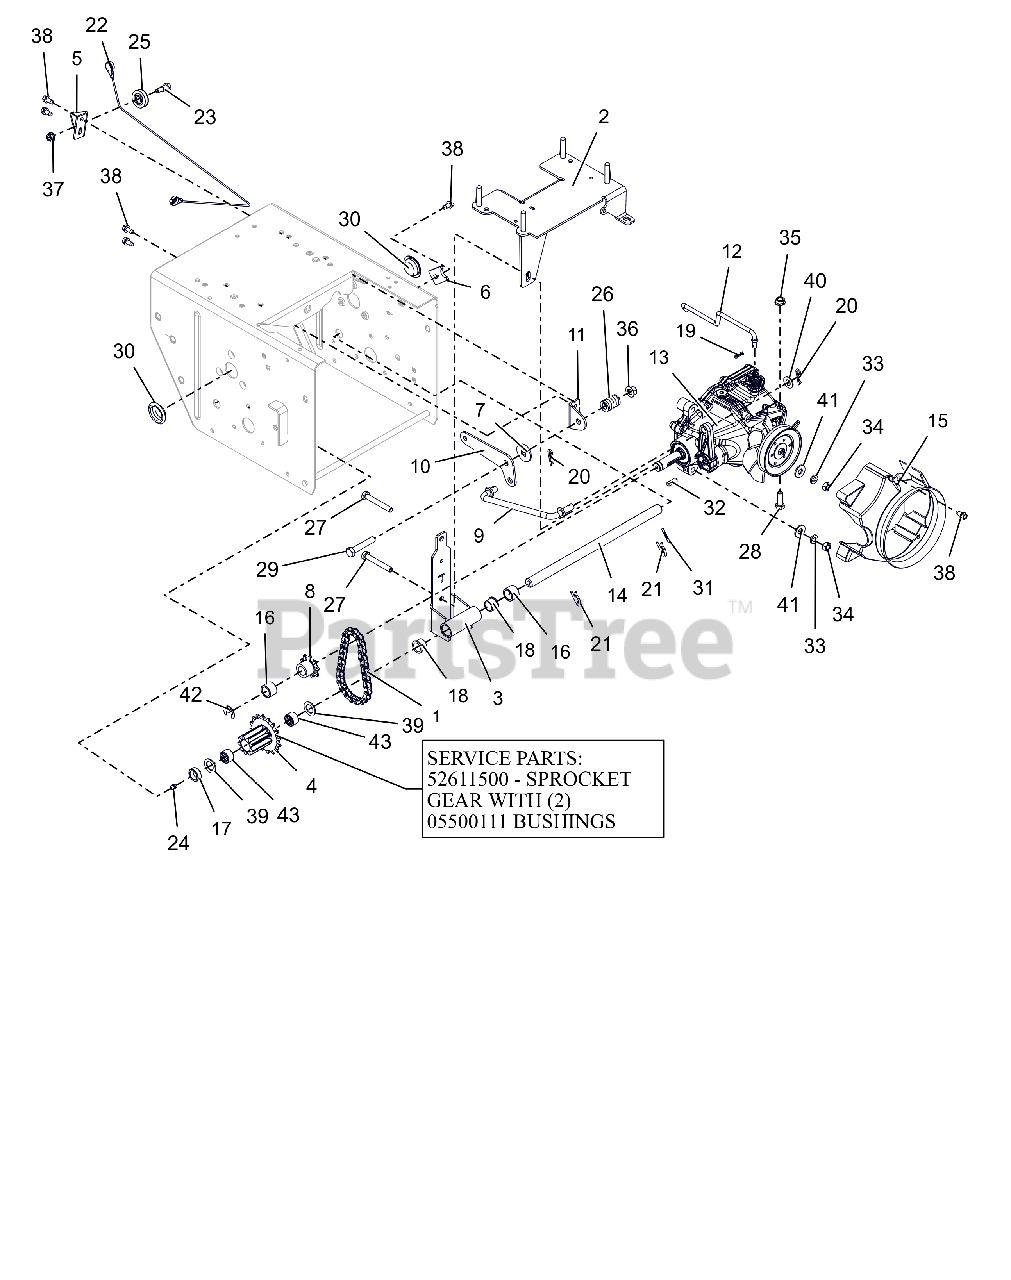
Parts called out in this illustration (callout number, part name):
1	CHAIN-ROLLER #41X26 PITCHES
2	BRACKET, HYDROSTATIC TRANS XLG
3	TRANS MOUNT, TENSIONING, TRACK
4	PINION & SPROCKET (16T & 9T)
4	PINION & SPROCKET W/BEARINGS
5	BRACKET, CABLE PULLEY
6	TAB, ANTI ROTATION
7	FRICTION WASHER
8	SPROCKET, PINION 9T W/KEY
9	ROD, HYDRO TRANS SHIFT
10	PIVOT, HYDRO TRANS SHIFT
11	BRACKET, HYDRO SHIFT PIVOT
12	ROD, HYDRO BYPASS
13	TRANSMISSION, HYDROSTATIC
14	SHAFT, PINION - HARDENED
15	SHROUD, HYDROGEAR RT-310
16	SPACER, .635X.880X.611
17	BSHG-SLV, .635X.880X.305
18	BSHG-FLG .625X.750X.500X.875
19	PIN-HAIR INT .06X.18X.77
20	PIN-HAIR INT .08X.18X1.18 YWZC
21	PIN, SPRING CLIP
22	CABLE, TRACTION, HYDRO PRO
23	BOLT, SHLDR-.375X.375X.25-20
24	ZERK,FITTING .25X.125 DRIVE IN
25	PULLEY, CABLE
26	SG-COMP .187X.56X1.62
27	@BLT-HEX .31-18X2.25 GR5 YWZC
28	@BLT-HEX .31-18X1.00 GR5 YWZC
29	@BLT-HEX .38-16X2.00 GR5 YWZC
30	PLUG, HOLE - 1.125"
31	@PIN-GRV .125X1.00 TP E ALLOY
32	KEY-SQ .188X.75X.188
33	WSHR-LK .312X.097 HVY YWZC
34	@NUT-HEX .31-18 YWZC
35	@NUT-LK-TOP-FLG .31-18 YWZC
36	@NUT-LK-TOP-FLG .38-16 YWZC
37	@NUT-LK-TOP-FLG .25-20 YWZC
38	SCR-TAP .25-20X.50 HWH TR YWZ
39	WSHR-FL-STL .630X1.005X.062 YZ
40	@WSHR-FL-STL.406X.812X.065 YWZ
41	@WSHR-FL-STL.38X.875X.083 YWZC
42	RG-RTNG-EXT .625X.042
43	BRG-NEEDLE .625X.812X.50
